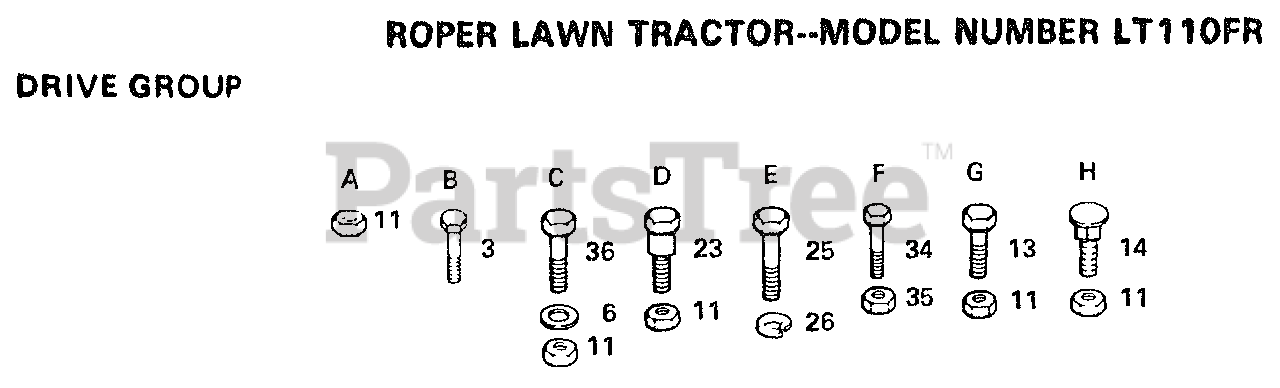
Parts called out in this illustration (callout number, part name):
3	SCREW
6	WASHER
14	BOLT
23	"BOLT, SHOULDER LT"
26	LOCKWASHER
34	BOLT
36	BOLT
